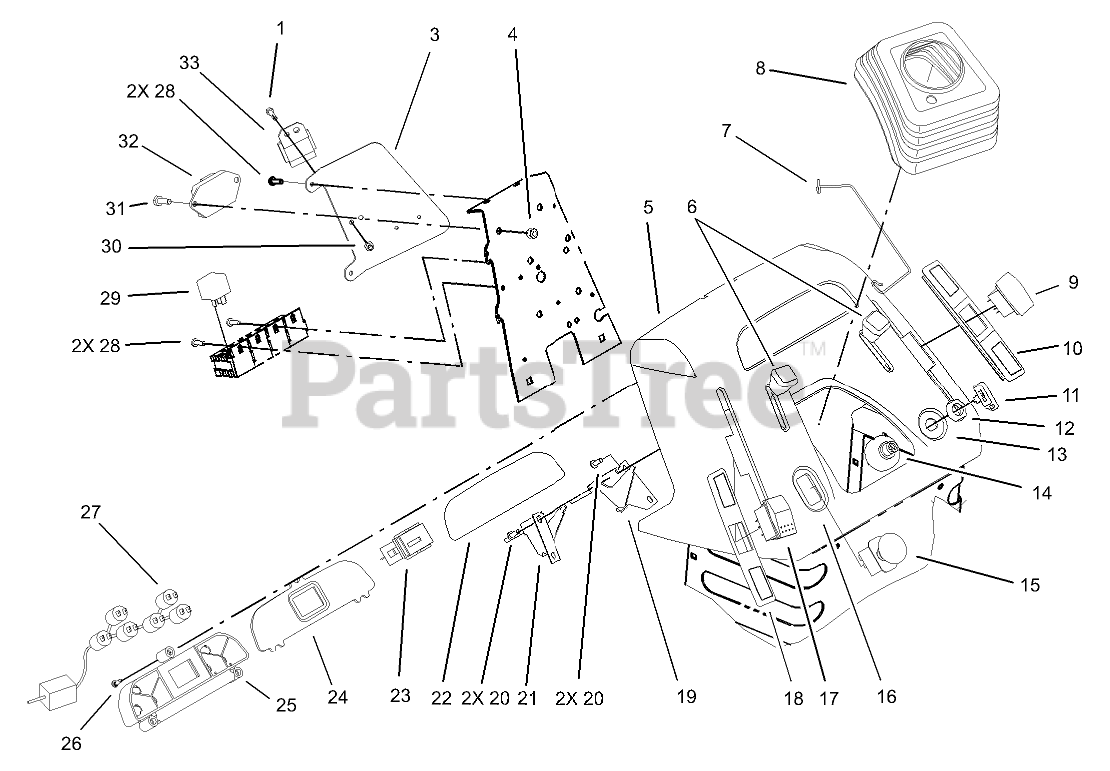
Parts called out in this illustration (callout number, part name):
3	PANEL-SUPPORT, AUX
4	NUT-LOCK, NI
7	CLIP-BOOT
8	BOOT-STEERING
9	SWITCH-CRUISE
10	Cover-RH Slot (only on: 72116)
10	Cover-RH Slot (only on: 72108)
11	KEY-IGNITION
13	Decal-Dash (only on: 72116)
13	Decal-Throttle, Ignition (only on: 72108)
14	SWITCH-IGNITION
15	SWITCH-PTO
16	Decal-Dash PTO/Choke (only on: 72116)
16	Decal-PTO/Choke (only on: 72108)
17	SWITCH
18	Cover-Lift (only on: 72116)
18	Cover-Lift (only on: 72108)
19	CONTROL-THROTTLE (TWIN)
21	CONTROL-CHOKE (TWIN)
22	DECAL - DASH LENS
23	HOURMETER
24	LENS-DASH
25	HOUSING-LIGHT
26	SCREW
27	HARNESS-6 LAMP
28	SCREW-PPHTF
29	RELAY
30	NUT-LOCK, NI
31	SCREW-HH
32	MODULE-CLUTCH
33	MODULE-LOW VOLTAGE
